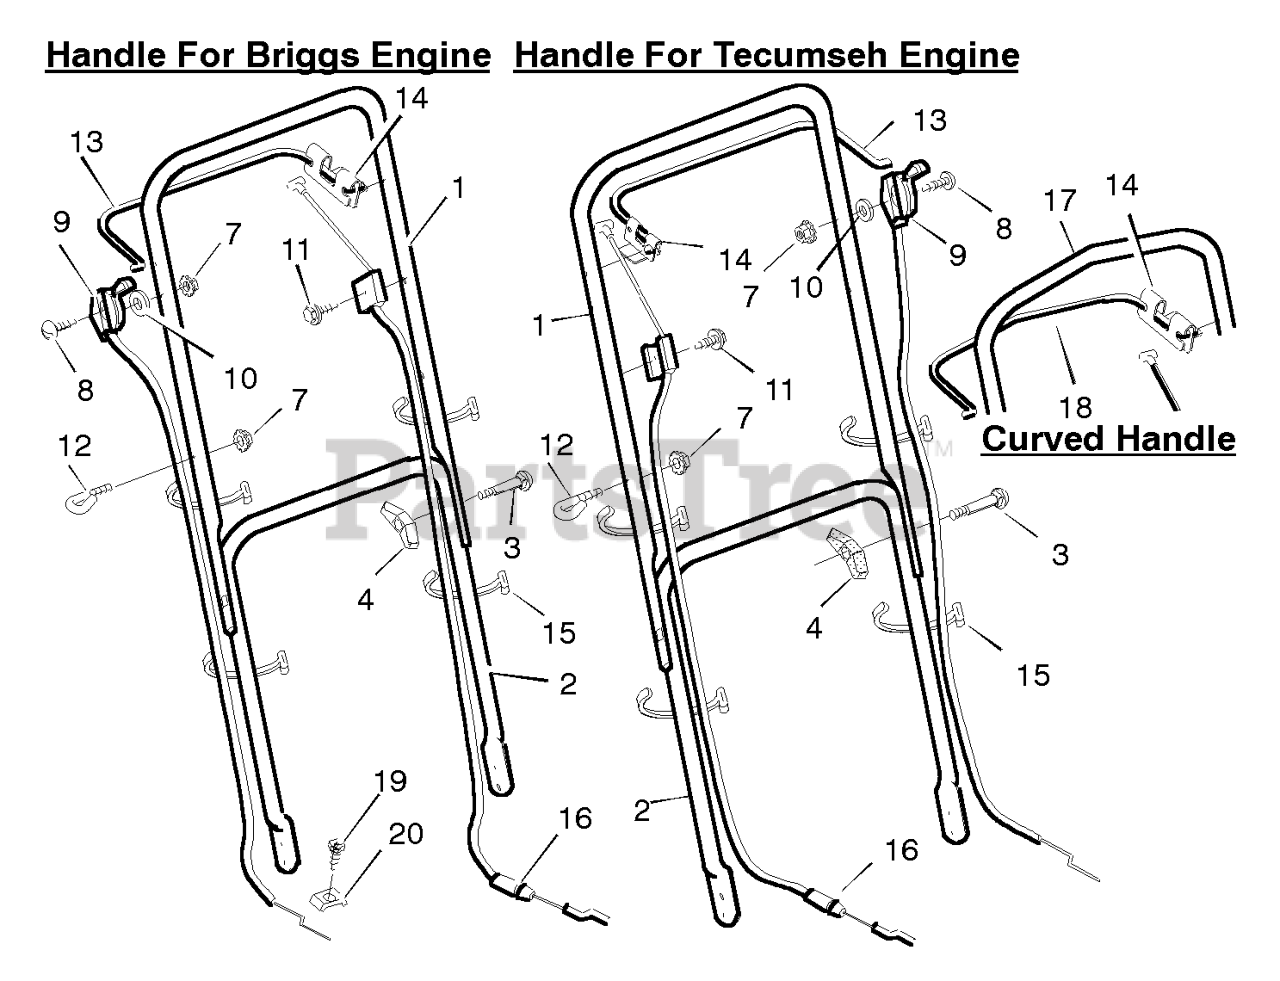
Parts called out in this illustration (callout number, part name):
1	Handle, Upper-Straight (Black)
2	Handle, Lower (Black)
4	Knob, Plastic
7	Locknut
9	Throttle Control
10	Washer
12	GUIDE, ROPE
13	Engine Stop Lever-Straight
14	Bracket, Stop Lever
15	Fastener, Cable
16	Engine Stop Cable *
17	Handle, Upper-Curved (Black)
18	Engine Stop Lever-Curved
19	Screw *
20	Clamp
